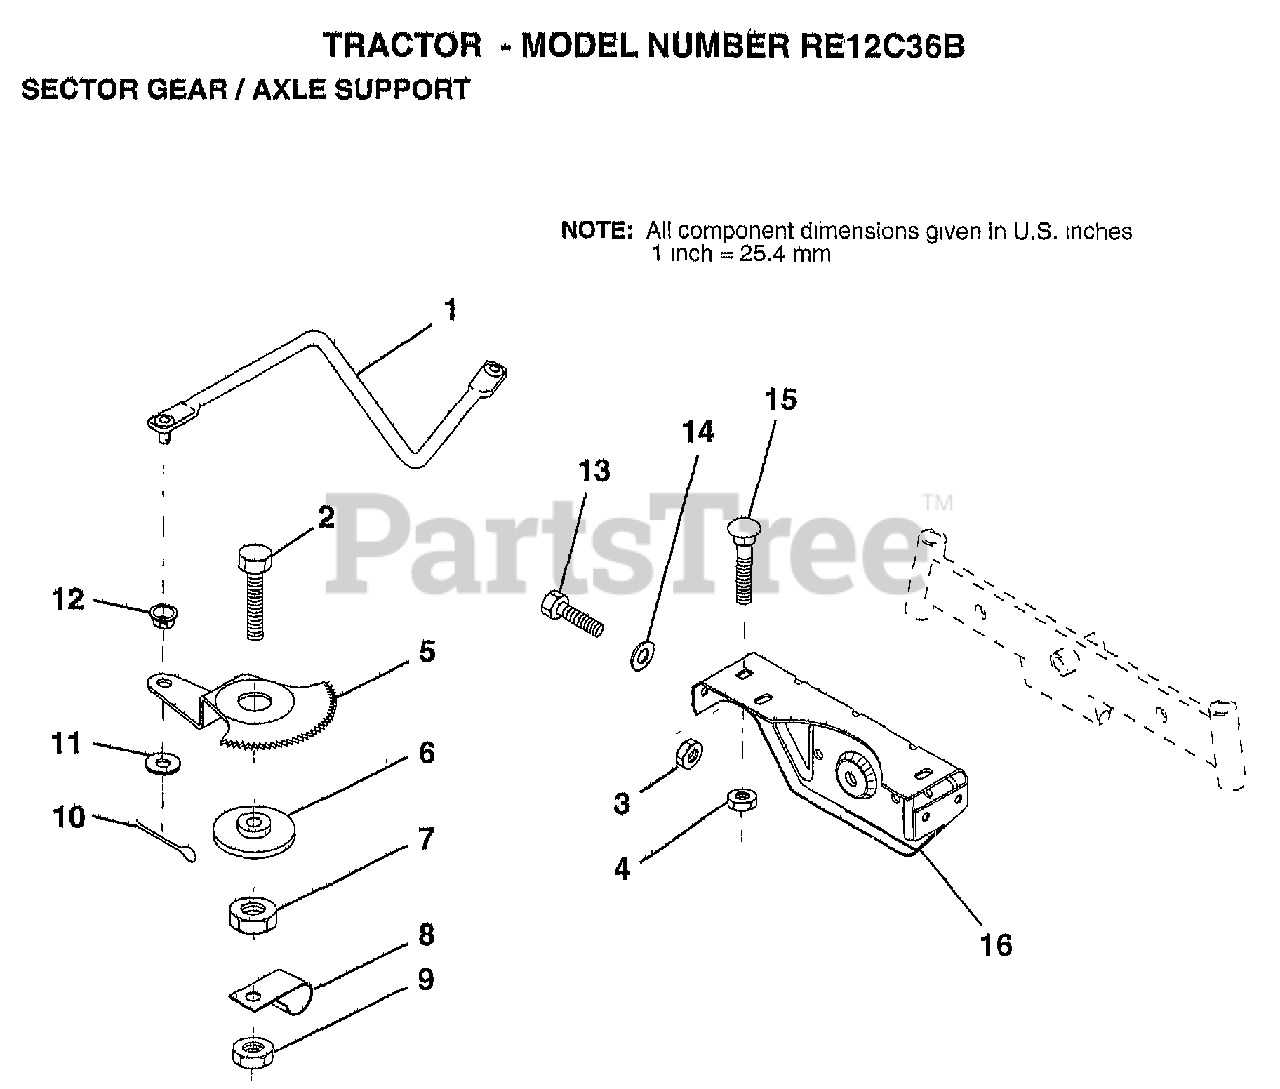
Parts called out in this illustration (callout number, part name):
1	DRAG LINK
2	"BOLT,HEX"
5	GEAR SECTOR
6	BUSHING
7	NUT
8	CLIP INSULATOR
9	NUT LTV
10	COTTER PIN
11	WASHER
12	BUSHING.DRAGLINK
13	BOLT
14	WASHER
15	BOLT
16	SUPT AXLE FRONT
